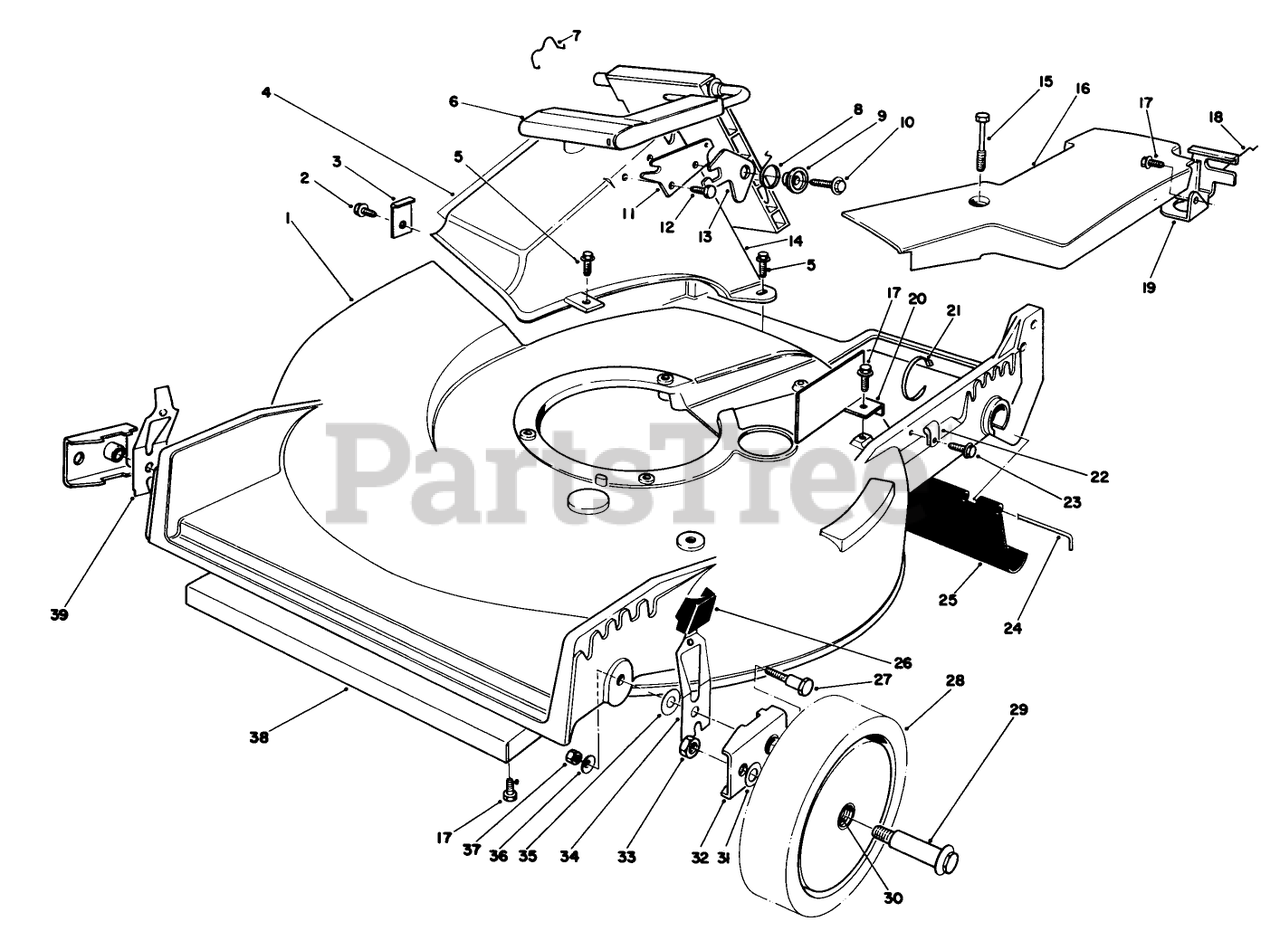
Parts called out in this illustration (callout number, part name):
1	21 SP RB HSG/DECAL
2	SCREW
3	TUNNEL CLIP
5	SCREW-HWH
7	DOOR RET SPRING
8	TORSION SPRING
9	DOOR SPACER
10	SCREW-HWH
11	DOOR LATCH PLATE
12	SCREW-PLASTITE
13	SAFETY LATCH
15	SCREW-HWH
17	SCREW-THD ROLL, HWH
18	RETAINER-CABLE
21	TIE-CABLE
22	CLAMP-CABLE
23	SCREW
24	ROD-SHIELD
26	KNOB-ARM
27	PIVOT SCREW
29	BOLT-WHEEL
30	BUSHING
31	WASHER
32	HP PIVOT ARM ASM
35	WASHER-PIVOT
36	WASHER-BELLEVILLE
37	NUT-LOCK, NI
